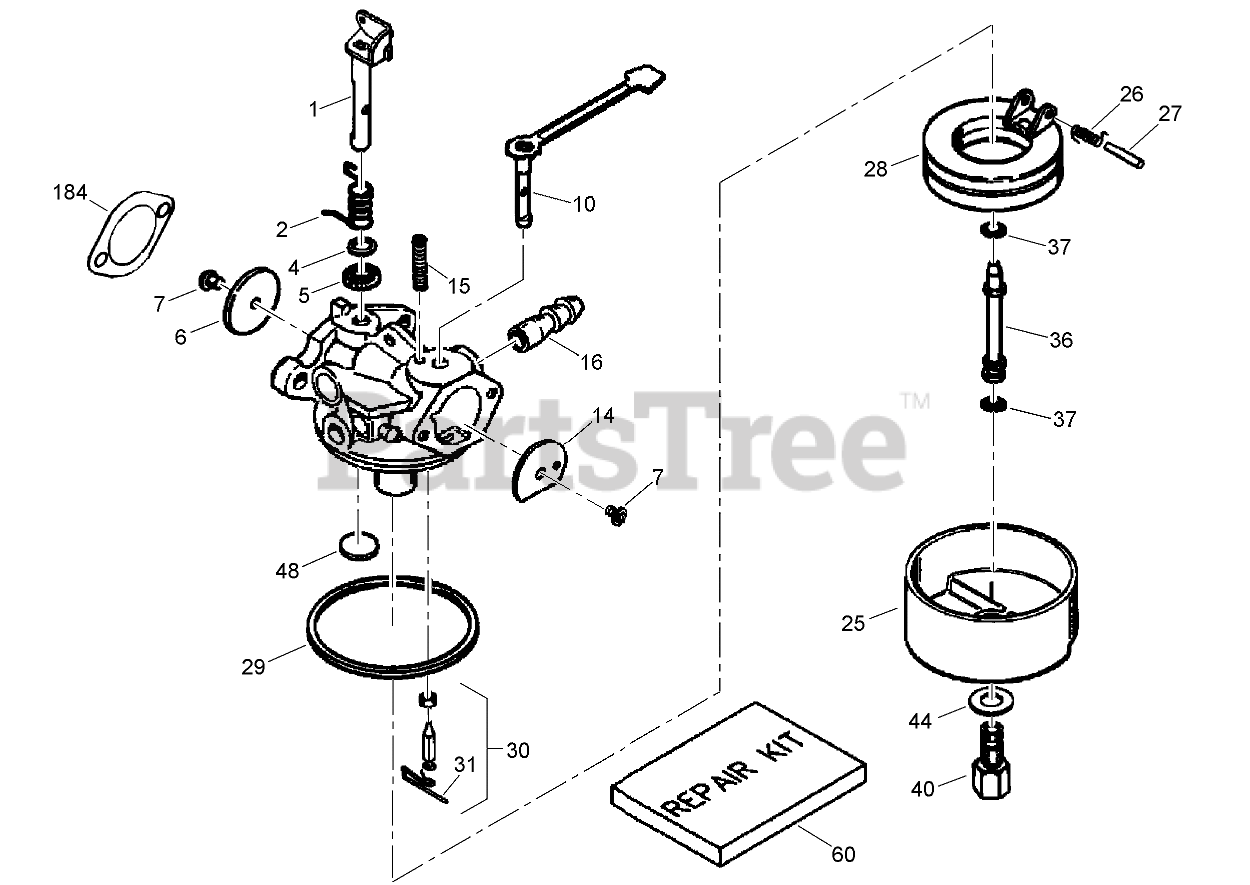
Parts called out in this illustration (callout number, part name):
1	Throttle Shaft and Lever ASM
2	Spring-Trottle, Return
4	Washer-Seal, Dust
5	Seal-Dust (Throttle)
6	Throttle-Shutter
7	Screw-Shutter
10	Choke Shaft and Lever ASM
14	Shutter-Choke
15	Spring-Positioning, Choke
16	Fitting-Fuel
25	Bowl-Float (no drain)
26	Spring-Float, Dampening
27	Shaft-Float
28	Float
29	O Ring-Bowl, Float
30	Inlet Needle, Seat and Clip Asm (Includes 31)
31	Clip-Spring
36	Tube-Nozzle, Main
37	O-Ring (Main Nozzle Tube)
40	Nut-Bowl, High Speed
44	Washer-Nut, Bowl
48	Plug-Welch, Atmospheric Vent
60	Repair Kit
184	Gasket-Carburetor
